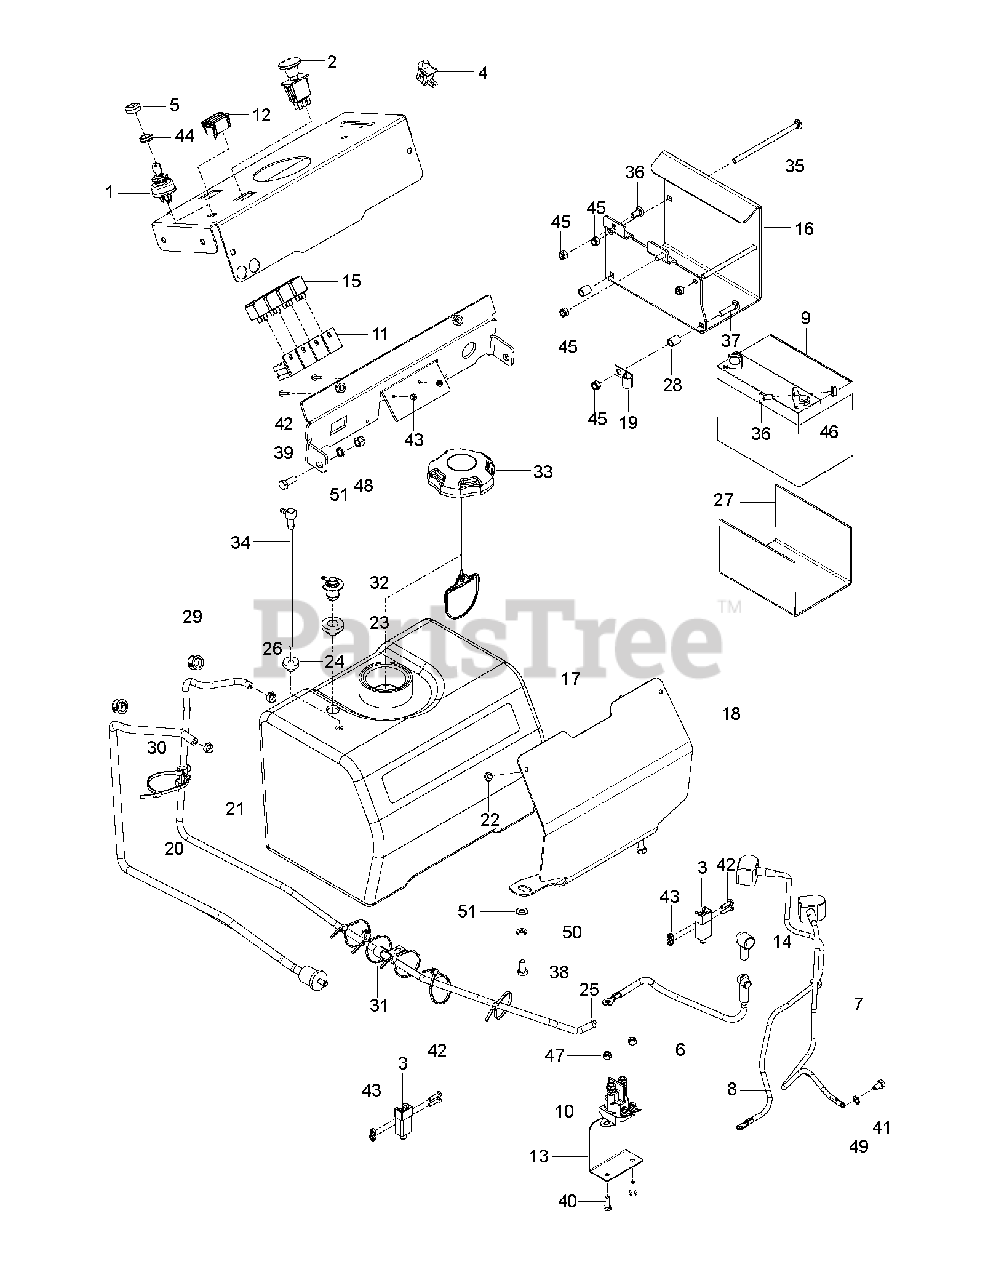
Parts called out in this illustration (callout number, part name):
1	SWITCH KEY-3 POSITION 180620
2	SWITCH CLUTCH (WITH GRAPHIC) 4
3	SWITCH NEUTRAL 00191256
4	SWITCH SEAT OVERRIDE (N.O.) SW
5	CAP CAP - IGNITION SWITCH
6	CABLE 12" STARTER 180842
7	CABLE BATTERY GROUND 25" 33879
8	CABLE BATTERY POSITIVE 25" 338
9	BATTERY 300 CCA 10U1L BATTERY
10	SOLENOID SOLENOID 3551000
11	HARNESS MY2011FSWLK ELE START
12	METER HOUR SMART SENSE W/O SV
13	COVER SOLENOID (GREY) 4225047
14	EYELET EYELET TERMINAL BOOT 75
15	RELAY ISO MINI ELEC. 102770
16	TRAY BATTERY ELEC 4450948
17	TANK TANK, FUEL LOW PERM HUSQ
18	SHIELD SHIELD, FUEL TANK HUSQ
19	CLIP P-CLIP, .500 INSULATED
20	HOSE HOSE, FUEL 1/4" X 32.75"
21	HOSE HOSE, VAPOR 3/16" X 56.00
22	BUMPER BUMPER GROMMET .125 X .
23	GROMMET GROMMET 2 WAY 04815500
24	GROMMET GROMMET, VITON
25	CLAMP CLAMP-HOSE, SPRING .188
26	CLAMP CLAMP, FUEL LINE
27	STRIP RUBBER D28159
28	BUSHING .364X.540X.700Y BUSHIN
29	BUSHING .687 X .875 X .56
30	CABLE CABLE TIE .19 X 14.4 967
31	CABLE TIE, .15 X 8.50 111910
32	VALVE VALVE 2 WAY 04815400
33	CAP CAP, FUEL NONVENT, AUTOLOC
34	FITTING FITTING, TANK
35	Round Head Bolt
36	BOLT BOLT RDHDSQNK .31-18X.75
37	BOLT BOLT RDHDSQNK .31-18 X 1.
38	BOLT BOLT HEX .38-16 X .75 GR5
39	BOLT BOLT HEX .38-16 X 1.00 GR
40	BOLT BOLT HEX .25-20X.75 GR5 Y
41	BOLT BOLT HEX M8 X 1.25 X 14
42	SCREW SCREW, MCH 10-24 X .75 H
43	NUT NUT, 10-24 KEPS
44	SERVICE PARTS SYSTEM NUT-PANEL
45	SERVICE PARTS SYSTEM NUT-LK-NY
46	SERVICE PARTS SYSTEM NUT-SPNLK
47	SERVICE PARTS SYSTEM NUT-LK-NY
48	NUT NUT, 3/8-16 NYLON LOCK ARI
49	WASHER WASHER, LK-E X T.326 X
50	WASHER WASHER, LK .38 X .094 R
51	WASHER WASHER, FL-STL .406 X .
52	SERVICE PARTS SYSTEM WASHER .3
